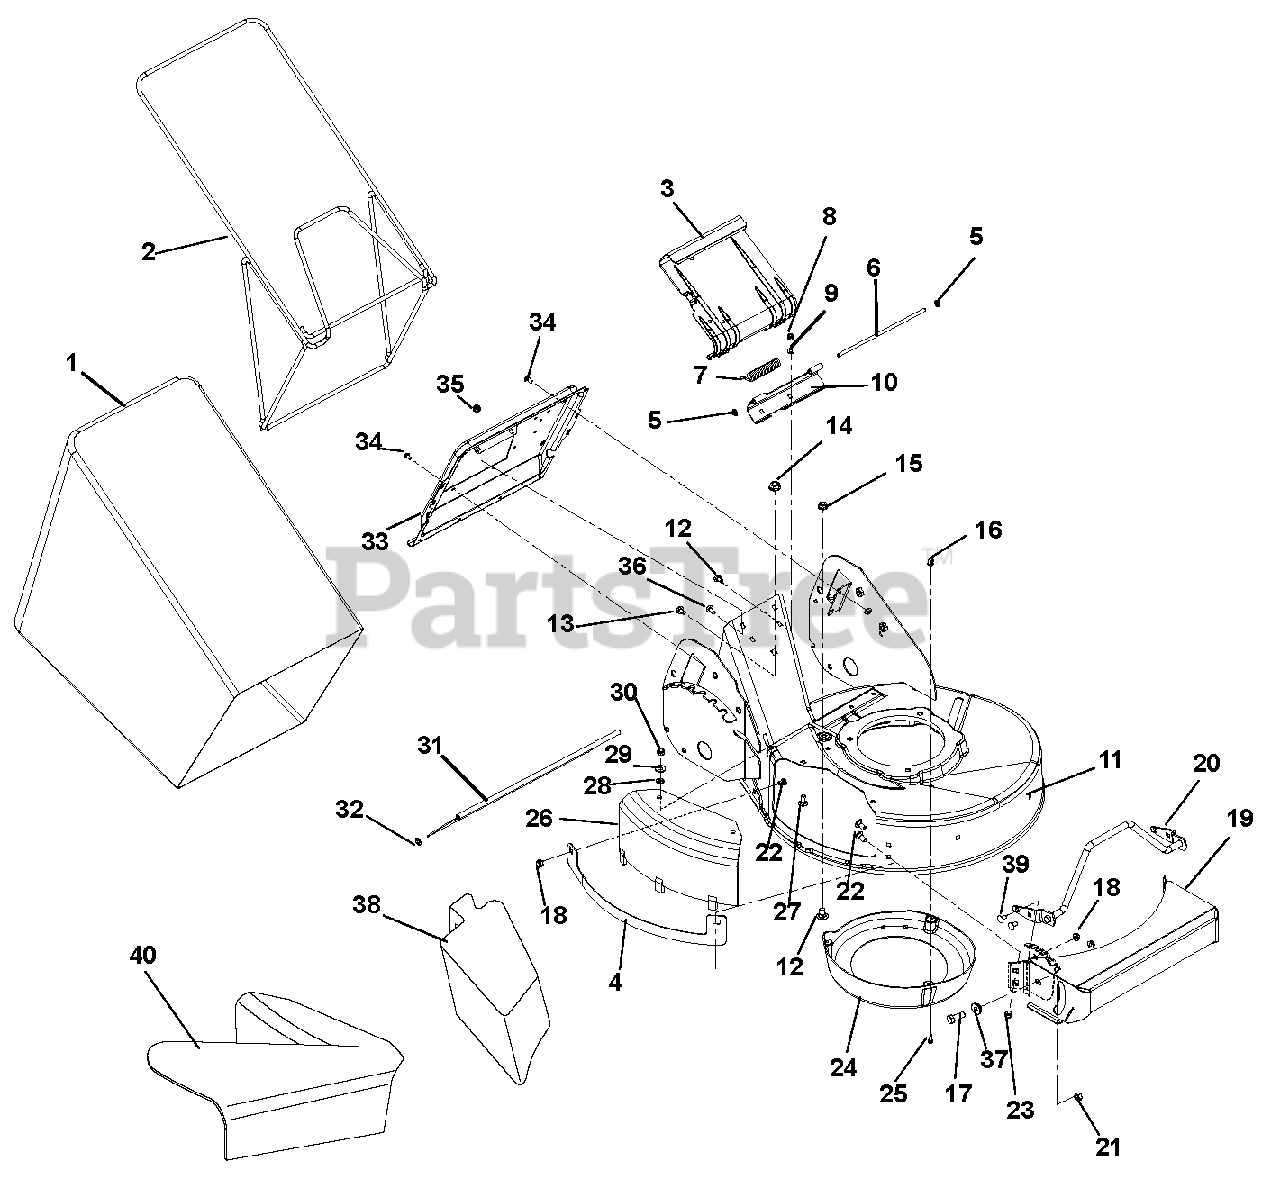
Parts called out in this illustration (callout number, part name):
1	Bag, Consumer Black 15 OZ/YD2
2	Frame, WBLM Bagger
3	Catcher Plate Door
4	Bracket, Discharge Guard
5	Push Nut, .25
6	Door Pin
7	Spring, Torsion .120 x .68 x 3.09
8	Nut, Hex .25-20
9	Washer, Locking .250 x .077 Heavy
11	Kit, XD21 Deck with Decals
12	Bolt, Hex .25-20 x .50
13	Bolt, Hex .38-16 x .50
14	Nut, Spin Lock, Flange .375-16
15	Nut, Locking, Flange .25-20
16	Plastic Grommet
17	Bolt, Hex .31-18 x 1.00
18	Nut, Locking, Top, Flange .31-18
19	Weldment, Commercial 21 Bumper
20	Angle, Support
21	Nut, Locking, Center .31-18
22	Bolt, Round Head Square Neck .31-18 x .75
23	Nut, Spin Lock, Flange .312-18
24	Center Baffle
25	Screw, Tapping 10-16 x .62 SLPH AB
26	Cover, Side Discharge
27	Bolt, Round Head Square Neck .31-18 x .75
28	Nut, Push .312
29	Washer, Flat, Steel .406 x .812 x .065
30	Nut, Locking, Nylon .312-18
31	Trailing Shield
32	Retainer, .38 Push-On
33	Catcher Plate
34	Screw, Tapping 1/4-20 x 3/4 LPAN
35	Nut, Locking, Flange .250-20
36	Bolt, Round Head Square Neck .25-20 x .50
37	Bushing, Flange .32 x .500 x .344 x .880
38	Plug, Mulchmaster Mulcher
39	Bolt, Round Head Square Neck .31-18 x .62
40	Side Discharge Assembly
